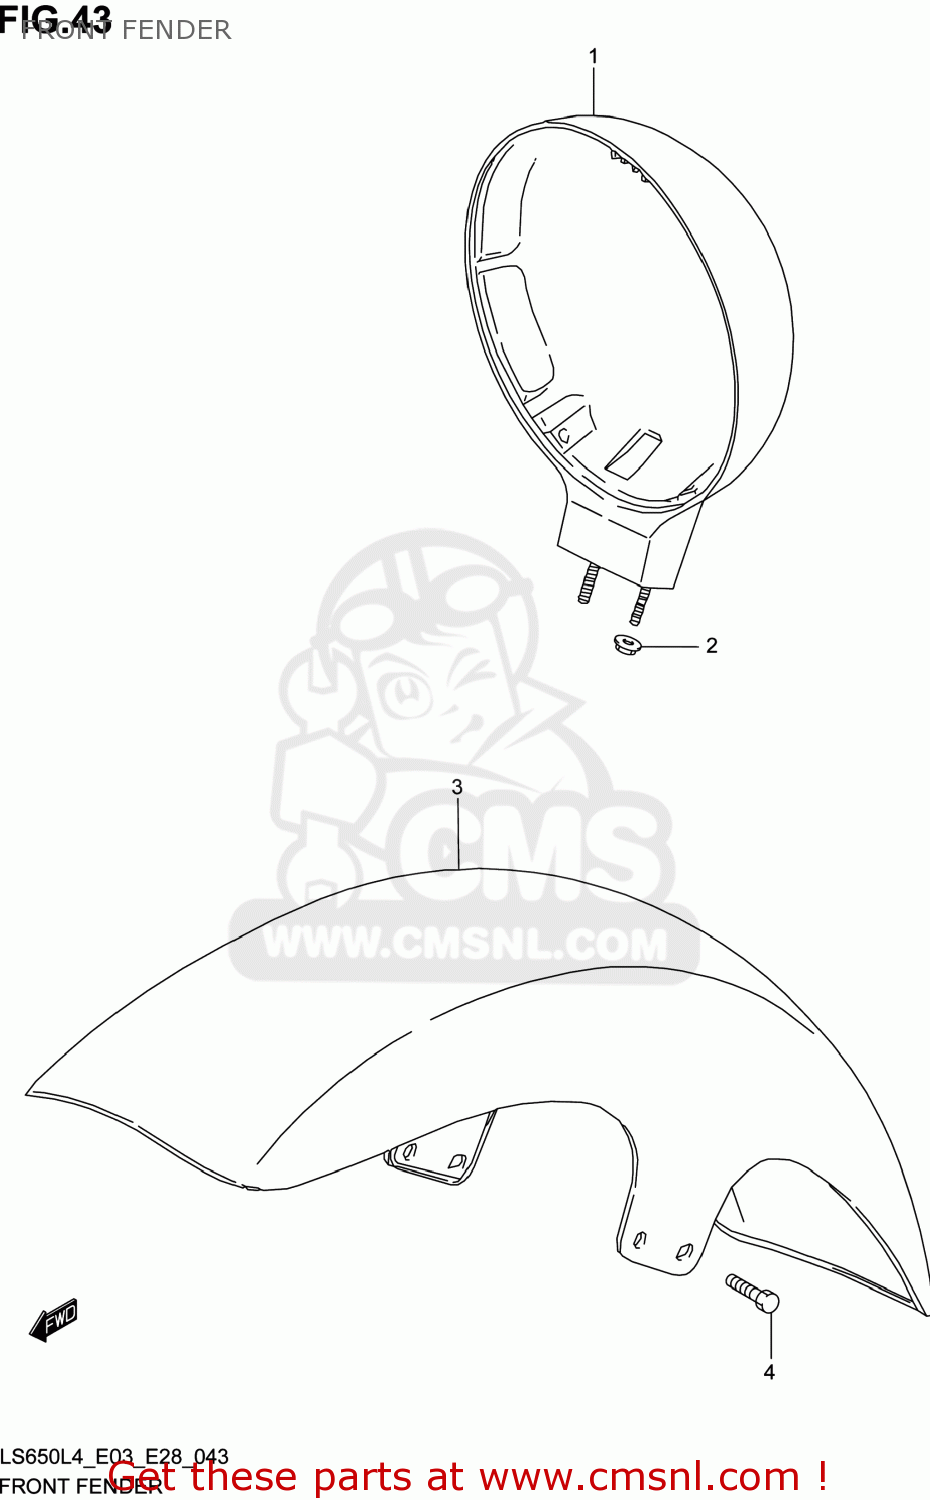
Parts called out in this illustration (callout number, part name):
1	HOUSING,HEADLAMP
2	NUT
3	FENDER,FR
4	BOLT
